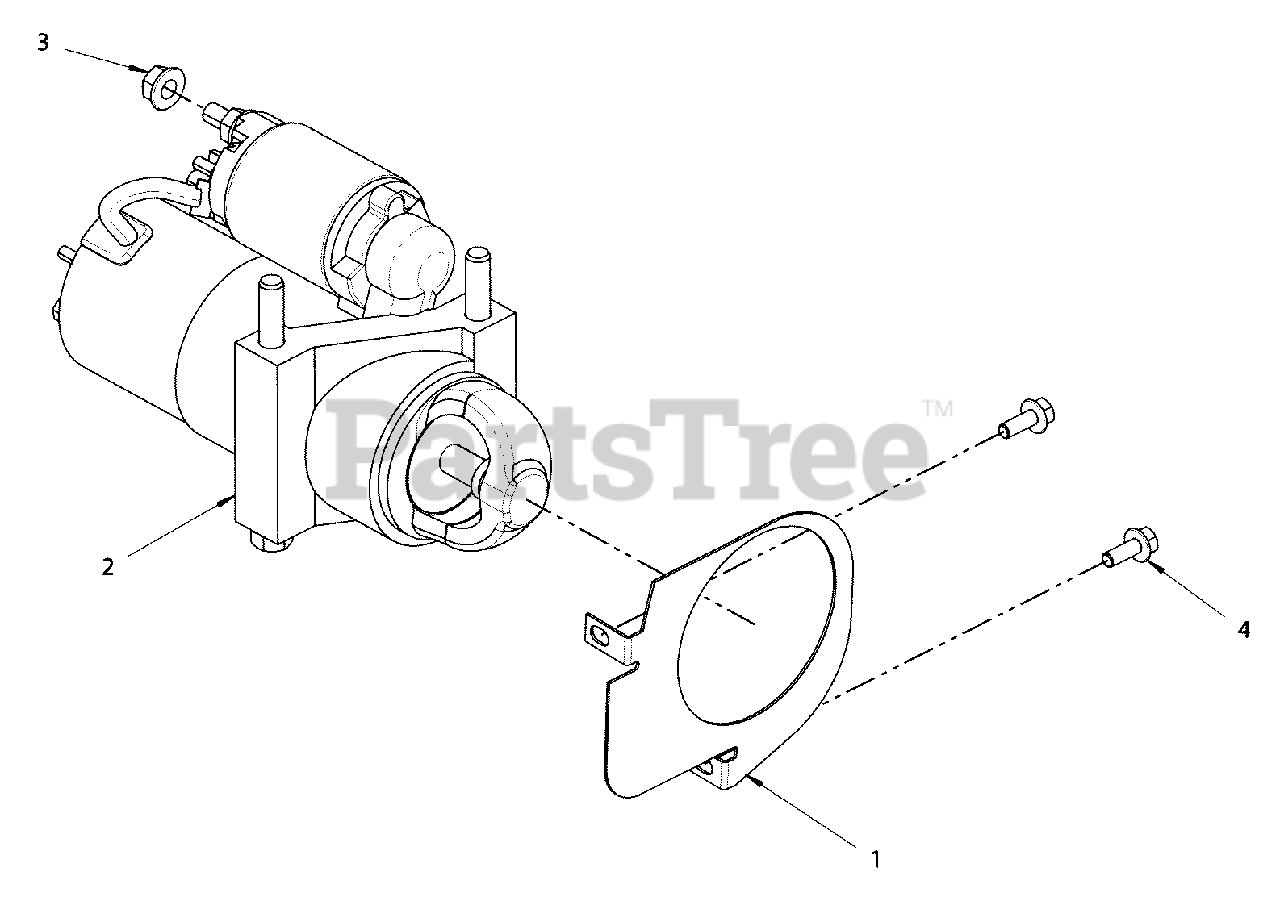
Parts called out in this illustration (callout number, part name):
1	COVER, STRTR MNT
2	STARTER
3	NUT, FLANGE
4	BOLT
